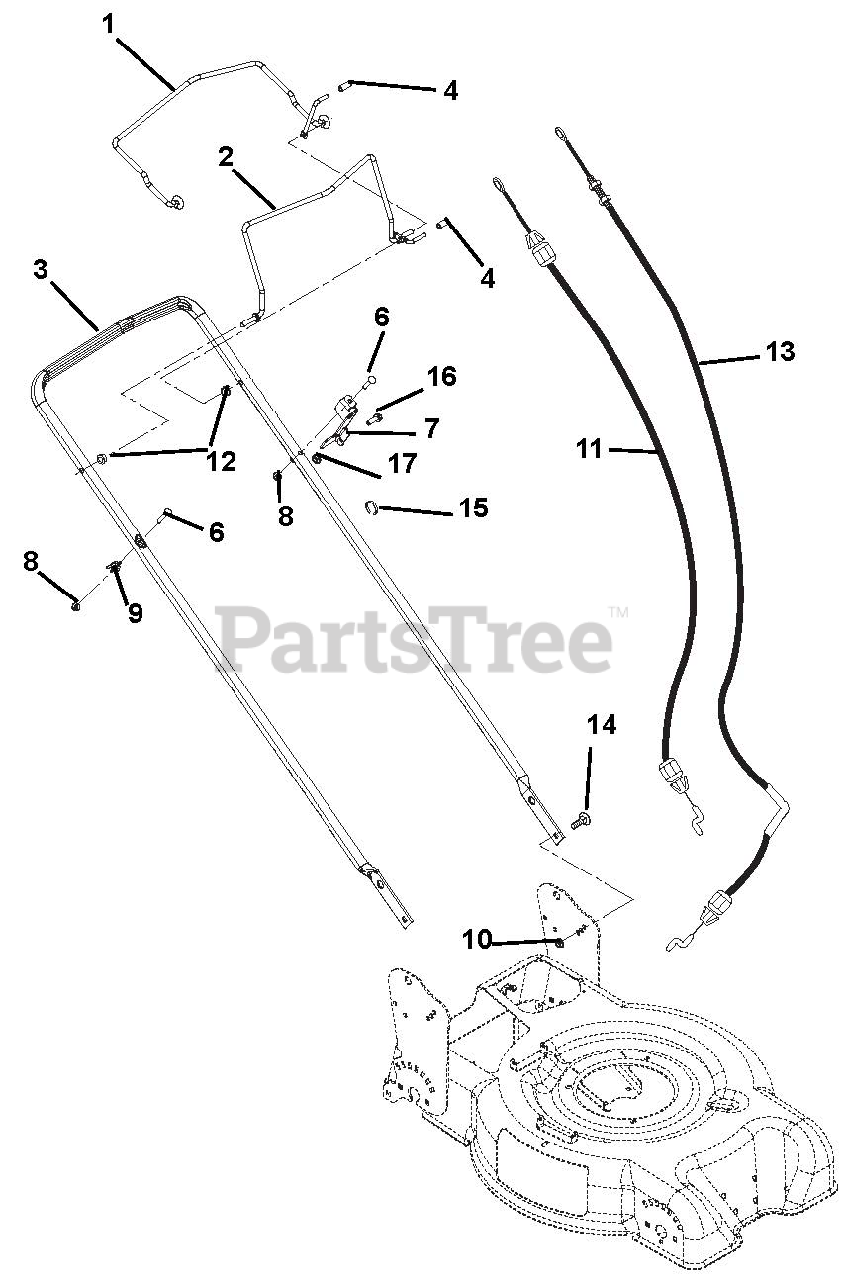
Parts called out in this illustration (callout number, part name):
1	BAIL, CLUTCH
2	BAIL, OPERATOR PRESENCE
3	HANDLEBAR, WBLM
4	CAP, VINYL, .25 ID
5	CAP, VINYL, .25 ID
6	BLT-RDHDXLSQNK.25-20X1.25 G5ZC
7	ANCHOR, CABLE - THUMB ADJUST
8	@NUT-LK-TOP-FLG .25-20 YWZC
9	GUIDE - PULLCORD
10	@NUT-SPNLK-FLG .312-18 YWZC
11	CABLE, KOHLER/BLADE RUNNER OPC
12	BSHG-FLG .325X.444X.440X.560
13	CABLE, TRACTION - THUMB ADJUST
14	@BLT-RHDSSQNK .31-18X.75 G5YZ
15	CONDUIT CLIP
16	@BLT-HEX .25-20X1.25 GR5 YWZC
17	@NUT-LK-TOP-FLG .25-20 YWZC
